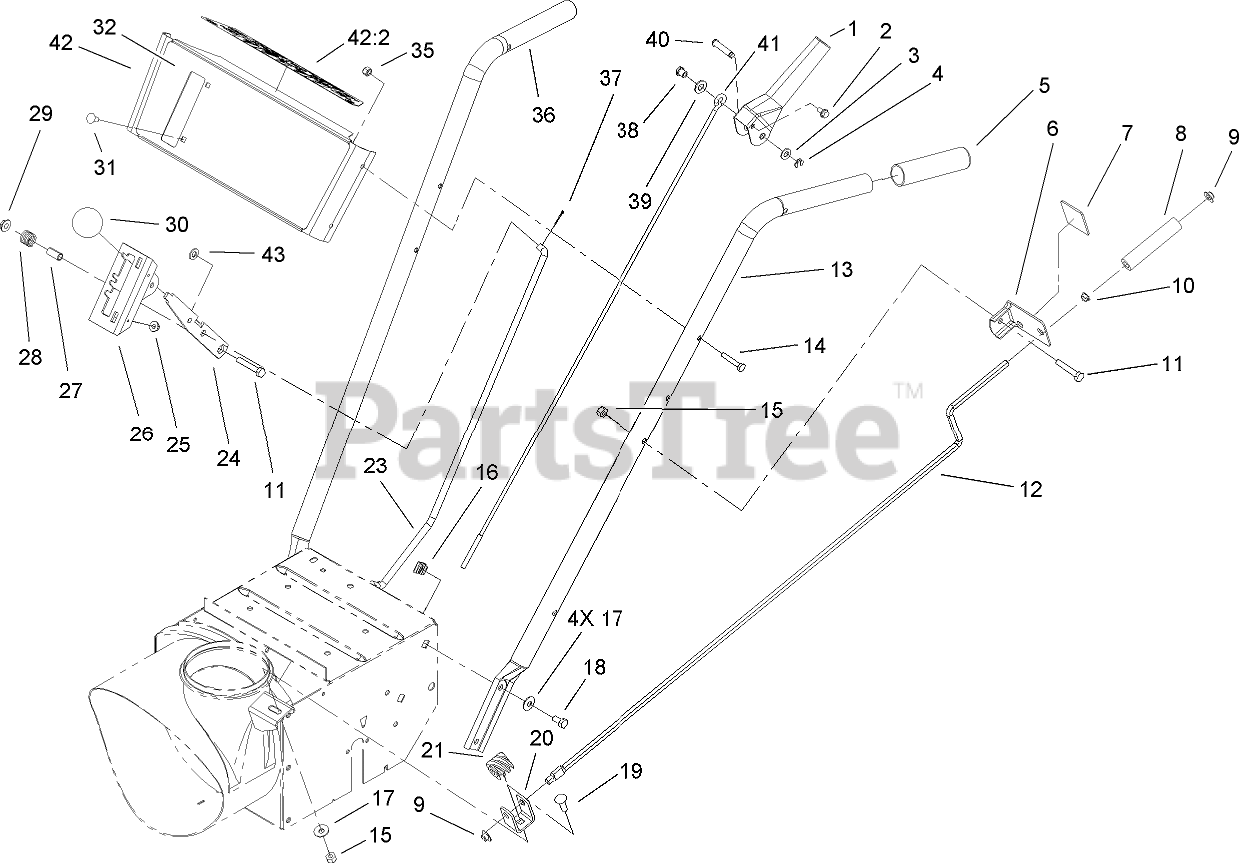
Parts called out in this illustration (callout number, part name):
1	HANDLE-CONTROL
2	SCREW-HHF
3	WASHER-PLAIN
4	RING-CLIP
5	GRIP-HANDLE
6	BRACKET-ROD, CHUTE
7	DECAL-CHUTE DIRECTION
8	GRIP-CONTROL, CHUTE
9	RETAINER-PUSH ON
10	Bushing
11	SCREW-HH
12	ROD-CONTROL, CHUTE
13	HANDLE-LEFT
14	SCREW-HH
15	NUT-LOCK, NI
17	WASHER-BELLEVILLE
18	SCREW-HH
19	SCREW-CARR
20	BRACKET-WORM
21	GEAR-WORM, CHUTE
23	ROD-SELECTOR, SPEED
24	Selector-Speed
25	NUT-HF
26	MOUNT-SELECTOR, SPEED
27	SPACER
28	SPRING
29	NUT-HF
31	SCREW-CARR
32	DECAL-ESCUTCHEON
35	NUT-LOCK, NI
36	HANDLE-RIGHT
37	PIN-COTTER
38	POST-MOUNTING, LINKAGE
39	WASHER-FLAT
40	PIN-LEVER, CONTROL
41	LINK-UPPER
42	ESCUTCHEON PANEL ASM
42:2	DECAL-ESCUTCHEON BACK
43	WASHER-PLAIN
